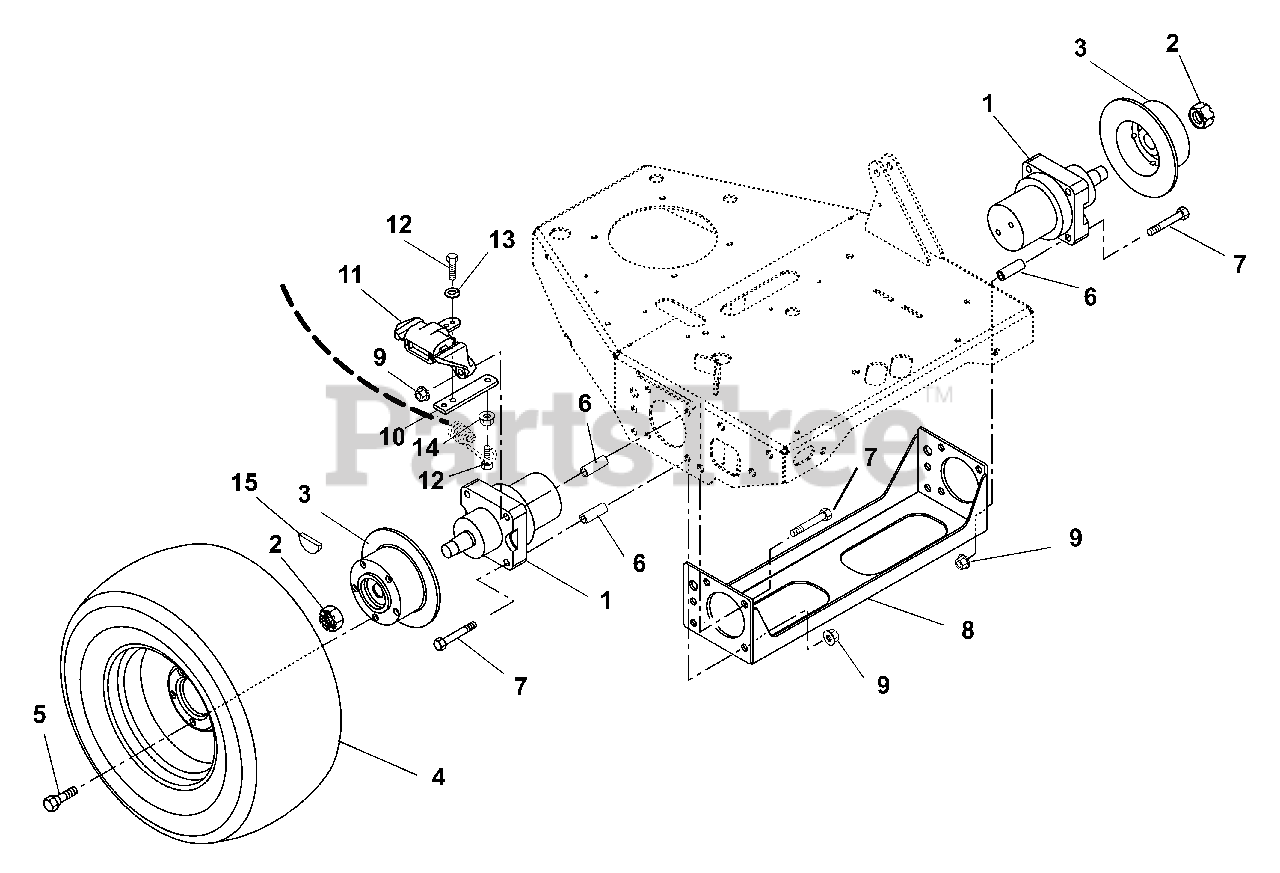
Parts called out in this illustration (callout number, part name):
1	Motor, Hydraulic Wheel
2	Nut, Locking-Jam-Patch 1.00-20
3	Hub and Disc
4	Tire/Wheel Assembly 24 x 12-12
4	Tire, Turfmaster 24 x 12-12
5	Bolt, Lug .50-20 x 1.38, Grade 8
6	Bushing-Sleeve .513 x .748 x 2.129
7	Bolt-Hex .50-13 x 5.00 Grade 8
8	Weldment, Wheel Support Bracket
9	Nut-Locking-Top-Flange .50-13
10	Arm, Extension Parking Brake
11	Caliper, Park Brake (Clockwise) Right Hand
11	Caliper, Park Brake (Counterclockwise) Left Hand
12	Bolt-Hex .31-18 x 1.00 Grade 5
13	Washer, Locking .31 x .078
14	Nut-Spin-Locking-Flange .312-18
15	Pad, Disk Brake
